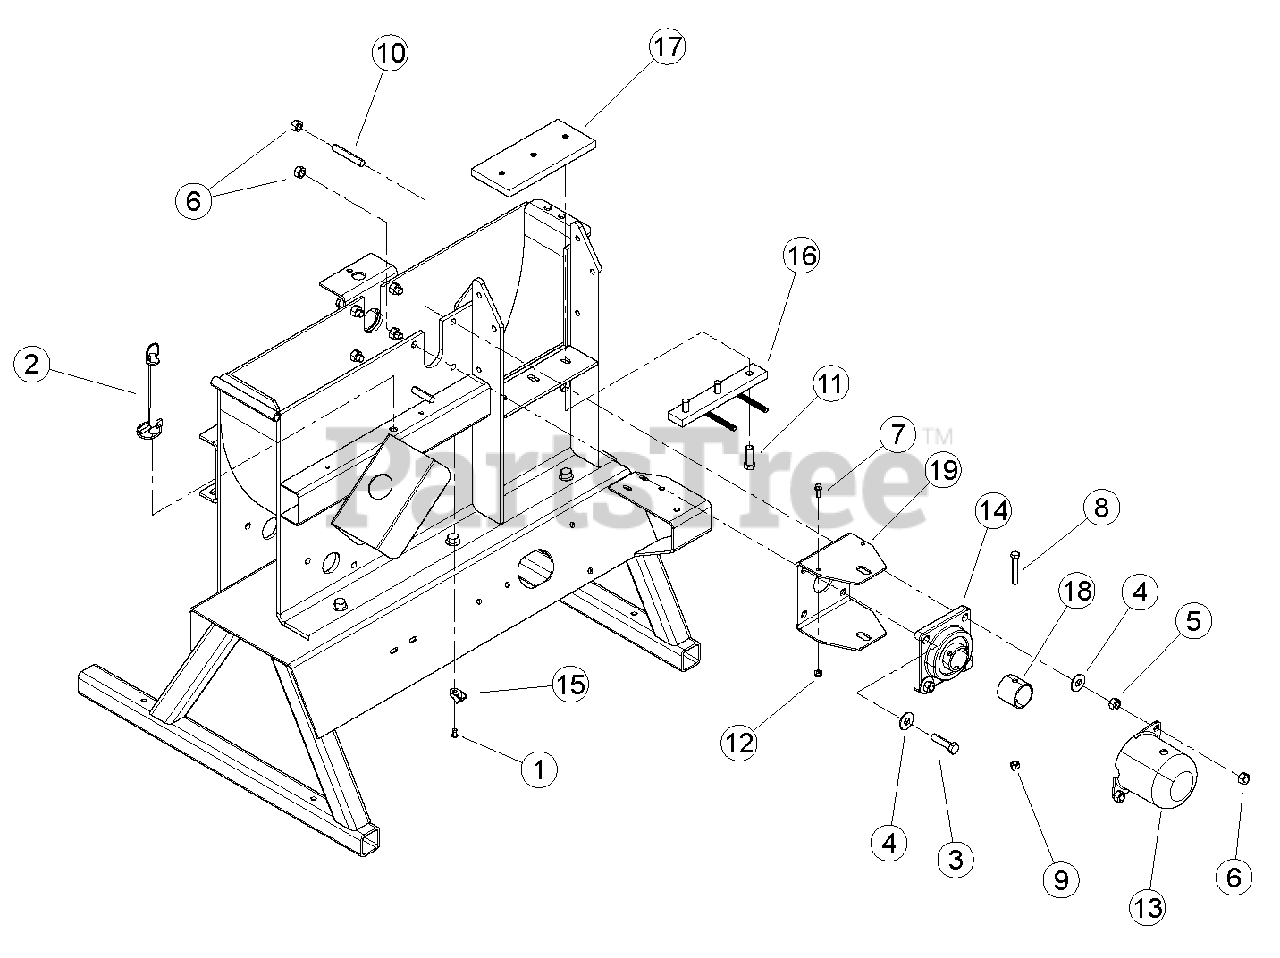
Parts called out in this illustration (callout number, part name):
1	RIVET, 1/4 X 3/4 ST POP
2	PIN, HITCH 1/2 X 6-1/2 W LYNCH
3	BOLT, 1/2 X 2 GR5 HEX CAPSCREW ZP
4	WASHER, 1/2" FLAT ZP
5	NUT, 1/2" HEX NC ZP
6	NUT, 1/2" CENTERLOCK GRB ZP
7	BOLT, 1/4-20 X 3/4 HWH GR5 CZP
8	BOLT, 3/8 X 2-1/2 GR5 HHCS ZP
9	NUT, 3/8" NE NYLOCK ZP
10	STUD, 1/2"-13 X 3" LG B7 ZP
11	BOLT, 1/2 X 1-1/2 GR8 NC ZP HEX HD
12	NUT, 1/4-20 NYLOCK-FLANGE
13	CAP, LARGE SHAFT
14	BEARING, 1-3/4 4 BOLT FLANGE
15	CLAMP, CABLE MOUNT
16	WELDMENT, BLOCK ADJUSTOR
17	PLATE, CHIPPER BOTTOM
18	COLLAR, CHIPPER LOCK
19	BRACKET, ROTOR LOCK
